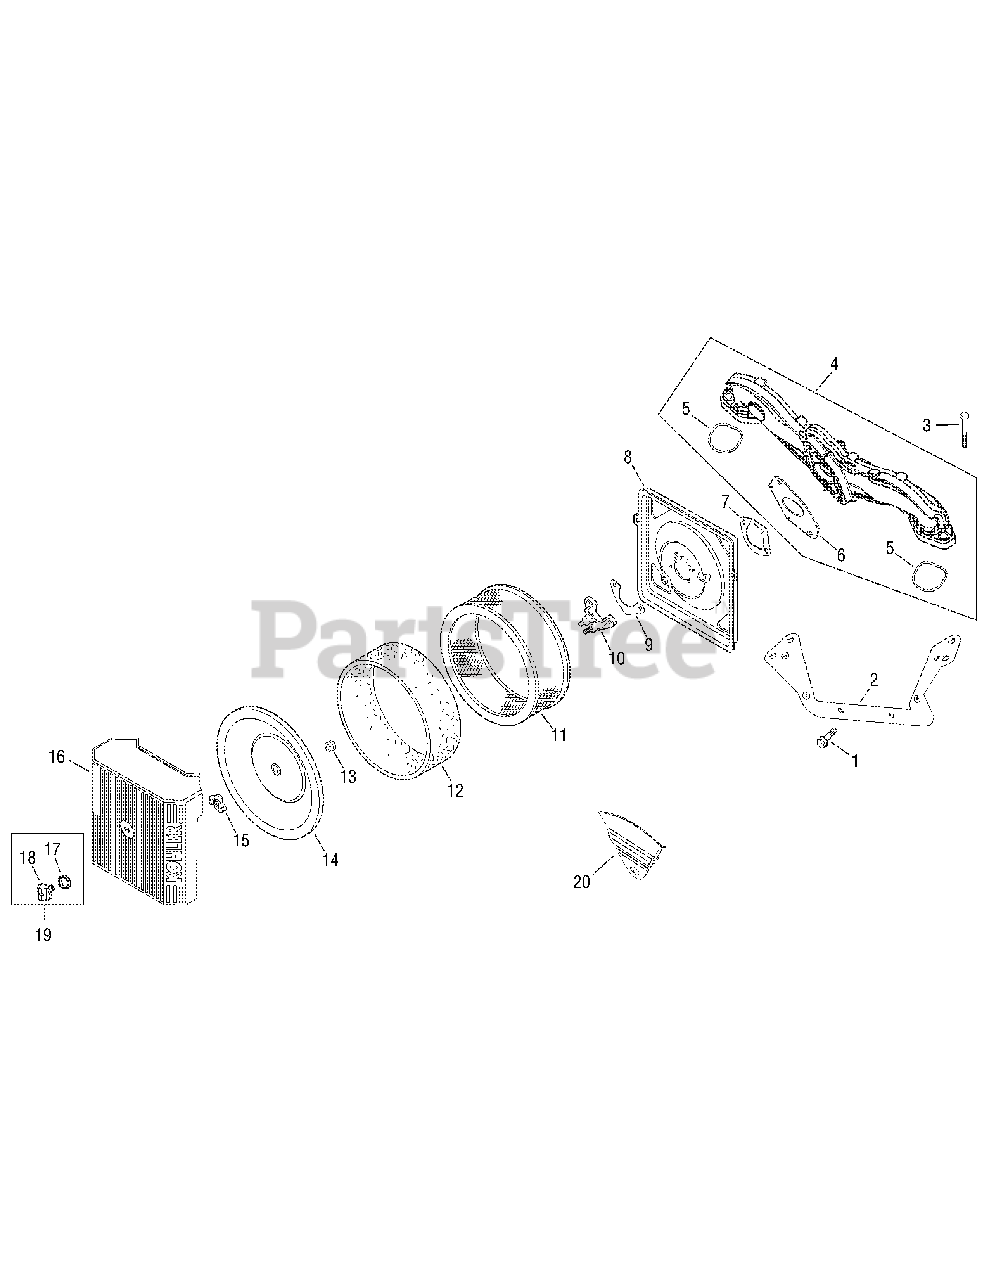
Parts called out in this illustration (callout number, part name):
1	Screw, hex. flange M5 x 0.8 x 10
2	Bracket, air cleaner base
3	Screw, hex. flange M6 x 1.0 x 40
4	Manifold, intake (Includes 5,6)
5	O-Ring, intake port
6	Gasket, intake manifold
7	Gasket, air cleaner base
8	Base, air cleaner
9	Gasket, fuel spit-back cup
10	Cup, spit-back w/stud
11	Element, air cleaner
12	Element, precleaner
13	Seal, breather
14	Cover, inner air cleaner
16	Cover, air cleaner
17	Kit, knob w/ seal (Includes 18,19)
20	Baffle, fuel spit-back
